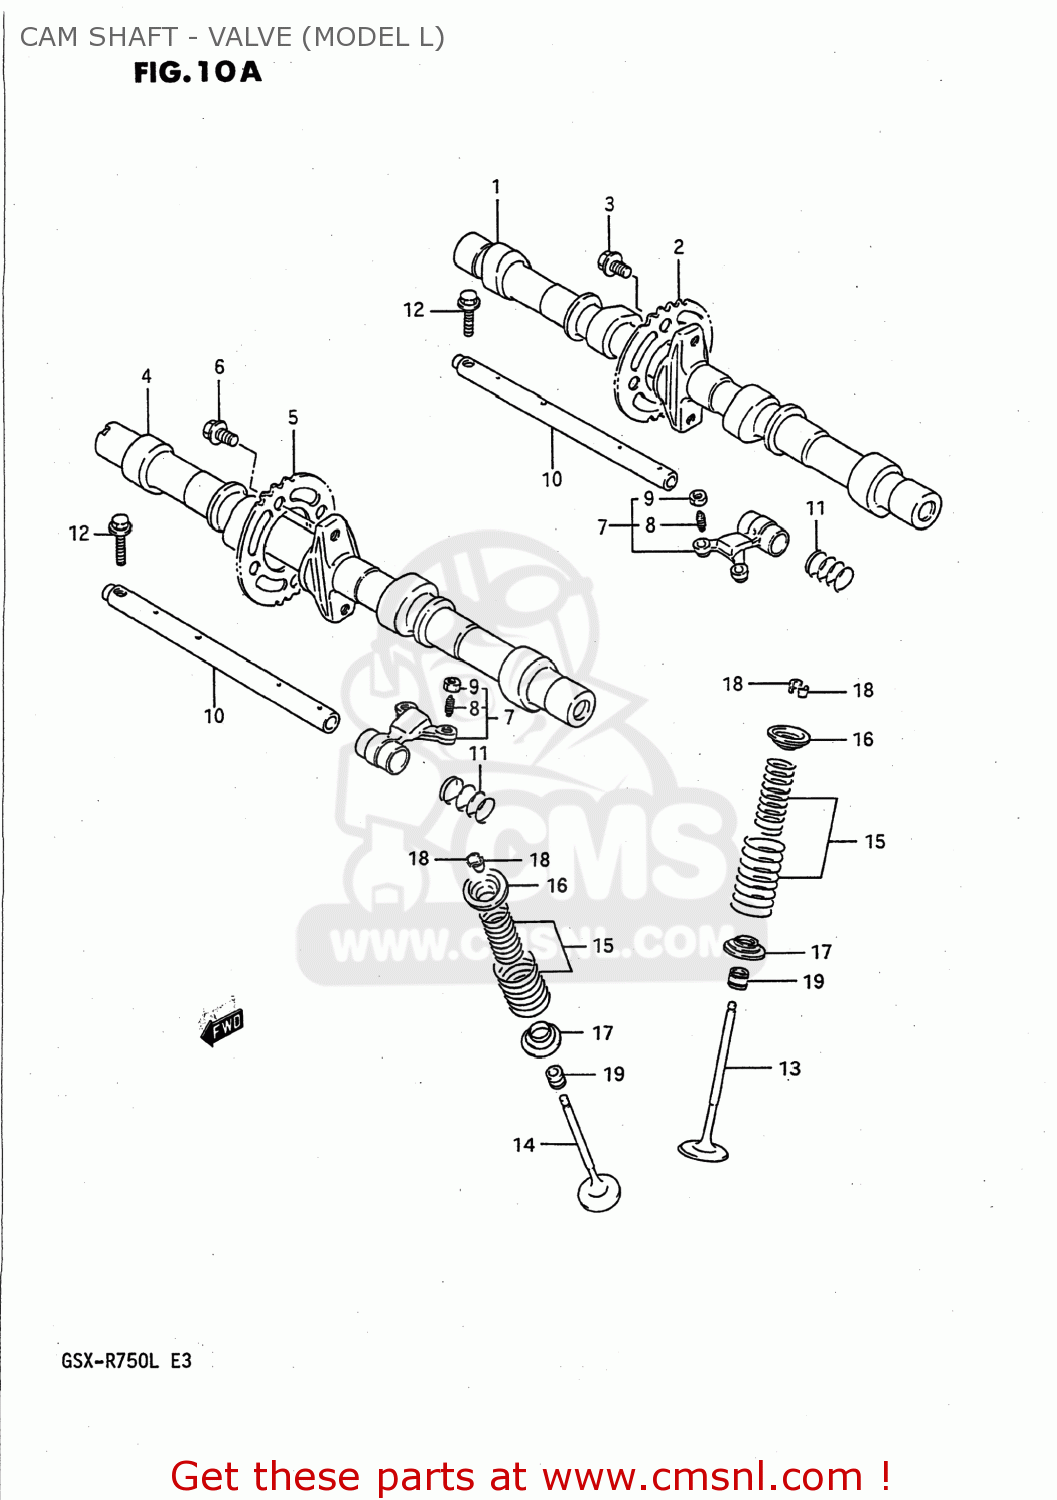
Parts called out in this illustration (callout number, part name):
1	CAMSHAFT
2	SPROCKET,CAMSHAFT
3	BOLT(7X11)
4	CAMSHAFT,EXHAUST
5	SPROCKET,CAMSHAFT
6	BOLT(7X11)
7	ARM,VALVE ROCKER
8	SCREW,TAPPET ADJUSTING
9	NUT,ADJUSTING
10	SHAFT,VALVE ROCKER ARM
11	SPRING
12	BOLT
13	VALVE,INTAKE
14	VALVE,EXHAUST
15	SPRING SET,VALVE
16	RETAINER,VALVE SPRING
17	SEAT,VALVE SPRING
18	COTTER VALVE
19	SEAL,OIL(5X10X9.7)
